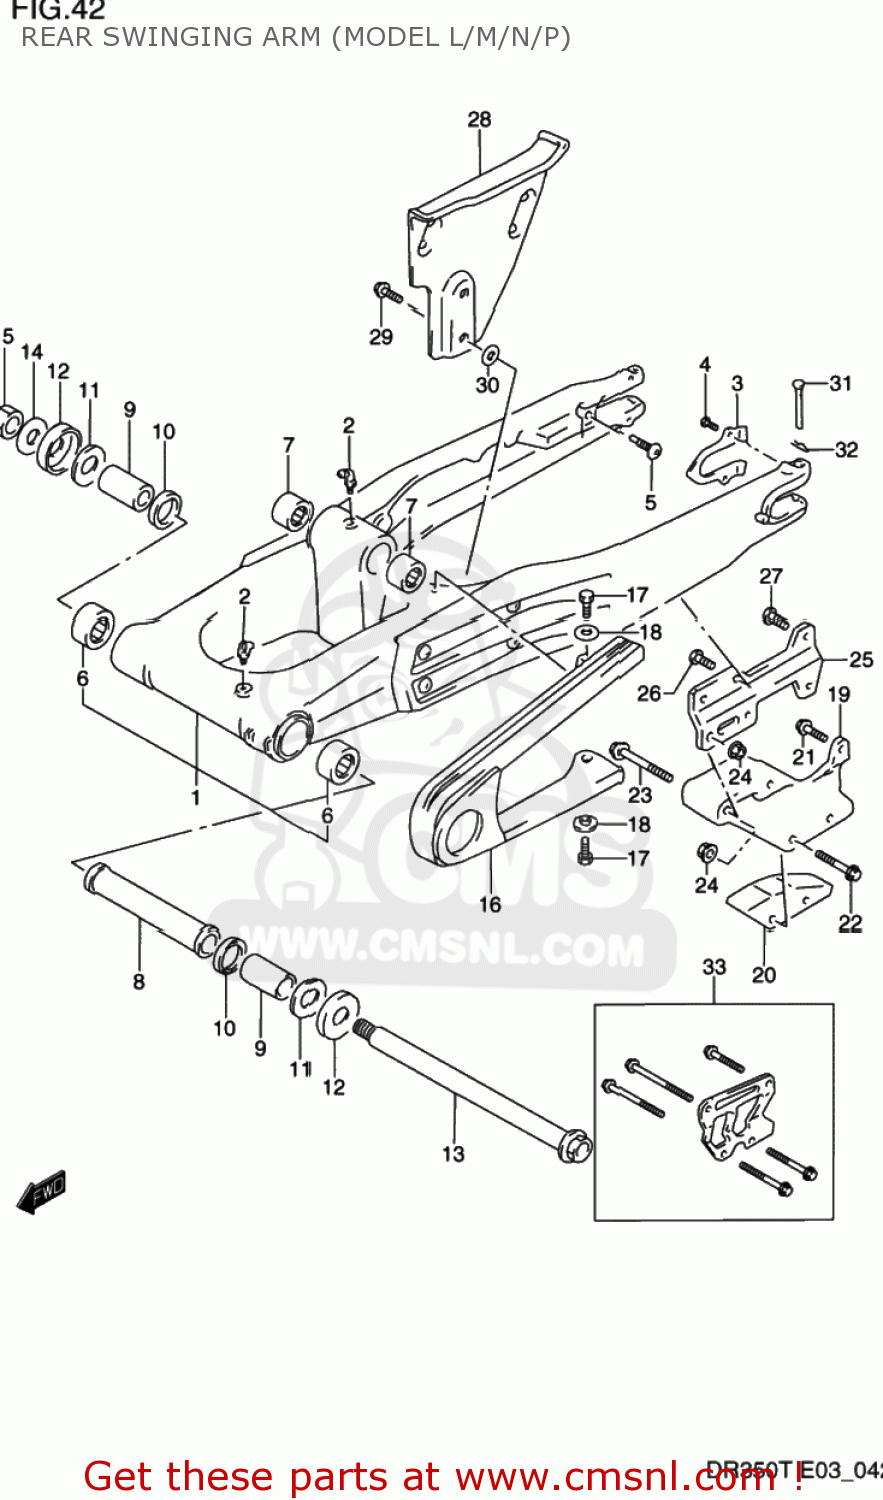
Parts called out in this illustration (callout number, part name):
1	SWING ARM ASSEMBLY,REAR
2	NIPPLE,GREASE
3	PLATE,SWING ARM RR
4	SCREW (5X8)
5	SCREW (M10X21)
6	BEARING(22X29X30)
7	BEARING(20X27X23.5)
8	SPACER,SWING ARM PIVOT,CENTER
9	SPACER,SWGARM PIVOT BRG
10	SEAL,OIL(22X29X4)
11	WASHER
12	COVER,SWINGINGARM PIVOT
13	SHAFT,SWINGING ARM PIVOT
14	WASHER
15	NUT
16	BUFFER,CHAIN TOUCH DEFENSE
17	BOLT
18	WASHER
19	GUIDE,CHAIN
20	DEFENSE,CHAIN GUIDE
21	BOLT 6X25
22	BOLT,UNDER
23	BOLT
24	NUT
25	BRACKET,CHAIN GUIDE
26	SCREW
27	BOLT
28	GUARD,CHAIN
29	BOLT
30	WASHER
31	PIN
32	CLIP
33	PLATE SET,CHAIN GUIDE
